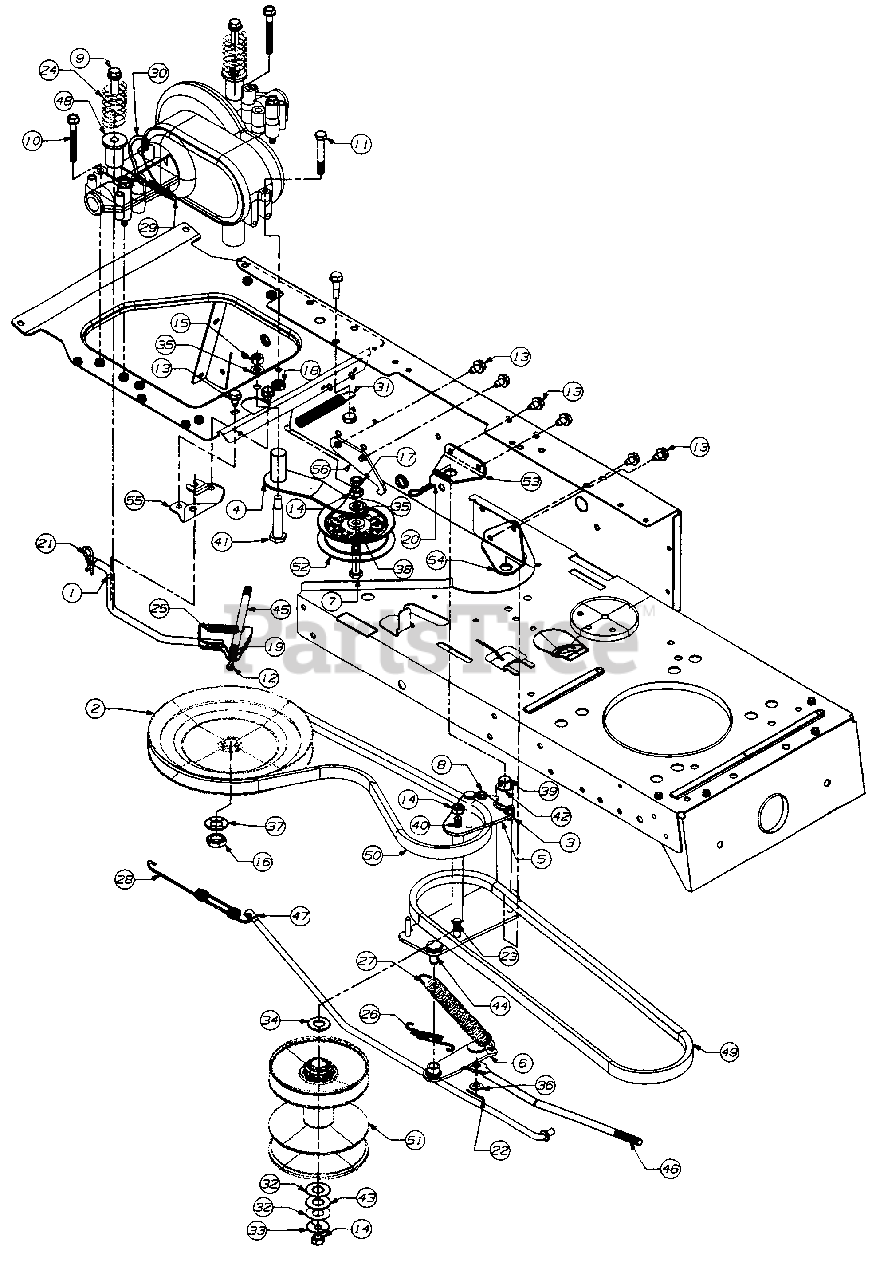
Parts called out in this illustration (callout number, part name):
1	Shift Lever Ass'y.
2	"V"-Pulley
3	Speed Brkt. Ass'y.
4	Idler Brkt. Ass'y.
5	Variable Speed Brkt. Ass'y.
6	Torque Brkt. Ass'y.
7	Hex Bolt 3/8-24 x 2.25" Lg. (Gr. 5)
8	Hex Wash. Hd. Tap Scr. 1/4-20 x .5" Lg.
9	Hex L-Wash. Hd. TT-Tap Scr 3/8-16 x 2.5" Lg.
10	Hex Wash. Hd. Tap Scr. 5/16-18 x 2.5" Lg.
11	Hex Bolt 5/16-18 x 2.25" Lg.
12	Hex Bolt #10-24 x .88" Lg.
13	Hex Wash. Hd. SF-Tap Scr. 5/16 x .5" Lg.
14	Hex Nut 3/8-24 Thd.
15	Hex Nut 3/8-16 Thd.
16	Hex Jam Nut 9/16-18 Thd. (Gr. 5)
17	Hex Jam L-Nut 3/8-24 Thd.
18	Hex Ctr. L-Nut 5/16-18 Thd.
19	Hex Sems Nut #10-24 Thd.
20	Hairpin Clip
21	Hairpin Clip
22	Cotter Pin 3/32" Dia. x 1" Lg.
24	Comp. Spring 2.3" Lg.
25	Comp. Spring 1.5" Lg.
26	Ext. Spring 2.54" Lg.
27	Ext. Spring 7.57" Lg.
28	Ext. Spring 7.08" Lg.
29	Ext. Spring 2.5" Lg.
30	Brake Return Anchor
31	Ext. Spring 4.74" Lg.
32	Fl-Wash. .56" I.D. x 1" O.D.
33	Bell-Wash. .39" I.D. x 1.13" O.D.
34	Fl-Wash. .565" I.D. x 1.12" O.D.
35	L-Wash. 3/8" I.D.
36	Fl-Wash. 5/16" I.D.
37	Bell-Wash. .567" I.D. x 1-18" O.D.
38	Fl-Wash. .411" I.D. x .812" O.D.
39	Shaft 8.62" Lg.
40	Shaft 6.92" Lg.
41	Shld. Bolt .5" Dia. x .433"
42	Flange Brg. .63" I.D.
43	Thrust Brg. .56" I.D.
44	Nyliner Flange Brg.
45	Shift Lever
46	Speed Control Link
47	Brake Rod
48	Step Spacer
49	"V"-Belt
50	"V"-Belt
51	Variable Speed Pulley
52	Flat Idler Pulley
53	Support Brkt. - Upper
54	Support Brkt. - Lower
55	Retainer - Shift Lever
56	Retainer Spring
